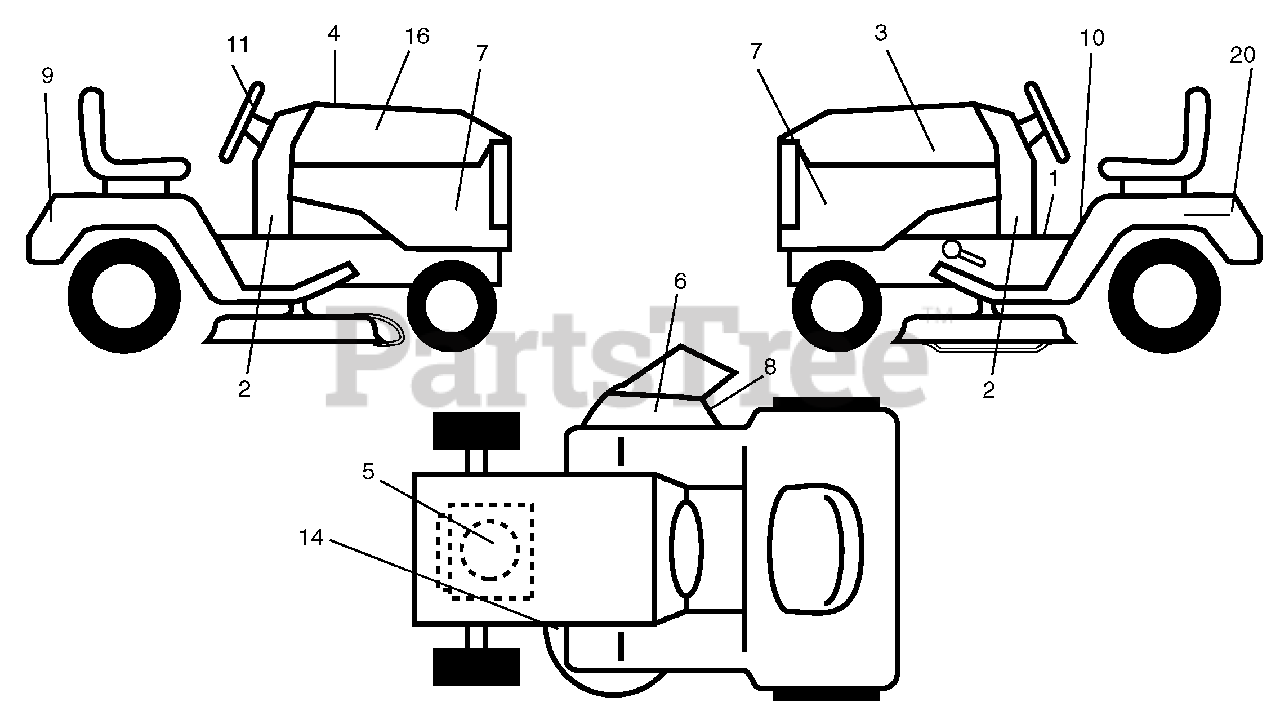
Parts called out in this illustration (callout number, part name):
1	Decal, Oper
2	Decal, Lower Dash
3	Decal, Hood LH
4	Decal, Replacement
5	Decal, HP Engine
6	Decal, Deck "B" 42"
7	Decal, Side Panel
8	Decal, Warning Mult-Language
9	Decal, Fender Logo
10	Decal, Fender Danger E/F
11	Decal, Ins Strg Whl
14	Decal, V-Belt Schematic
16	Decal, Hood Rh
20	Decal, Bat Dan/Psn
20	Decal, Handle Lft Height Adjust
20	Manual, Operator's E&F
20	Manual, Parts E&F
